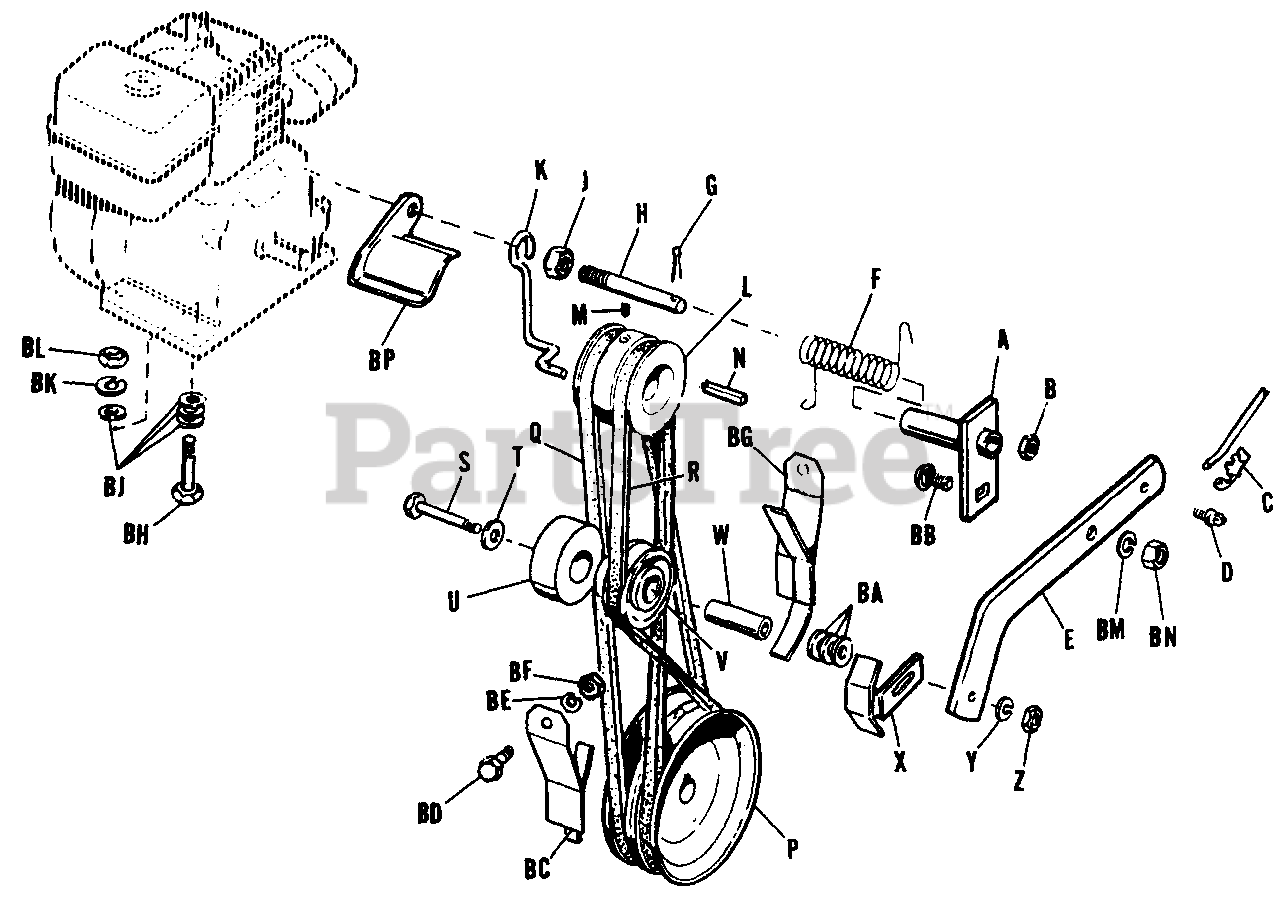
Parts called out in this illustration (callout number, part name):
A	Support Assembly, Idler Lever
B	Hex Nut, Full Lock, 1/4-20
C	Clip, Rod Clevis
E	Lever, Idler
F	Spring, Idler Lever
G	Cotter Pin, 1/8" x 1"
H	Engine Stud
J	Hex Jam Nut, 1/2" NF
K	Belt Stop
L	Drive Pulley
M	Set Screw, Socket Hd, 5/16-18 x 5/16
P	Driven Pulley
Q	V-Belt,"Forward"
R	V-Belt,"Reverse"
S	Capscrew, Hex Hd, 3/8-16 x 3"
T	Washer, Plain, 3/8"
U	Pulley Assembly, Idler
V	Pulley Assembly, Reverse Idler
X	Belt Retainer
Y	Lock Washer, 3/8"
Z	Hex Nut, Full, 3/8"-16
BA	Washer, Plain, 3/8"
BB	Carriage Bolt, 3/8-16 x 1"
BC	Belt Guard
BD	Capscrew, Hex Hd, 3/8-16 x 3/4"
BE	Lock Washer, 3/8"
BF	Hex Nut, Full, 3/8"-16
BG	Guard Assembly, Reverse Belt
BH	Capscrew, Hex 5/16-18 x 2"
BJ	Washer, Plain, 5/16"
BK	Lock Washer, 5/16"
BL	Nut, Hex, Full, 5/16-18
BM	Lock Washer, 3/8"
BN	Hex Nut, Full, 3/8-16
BP	Guard, Belt
